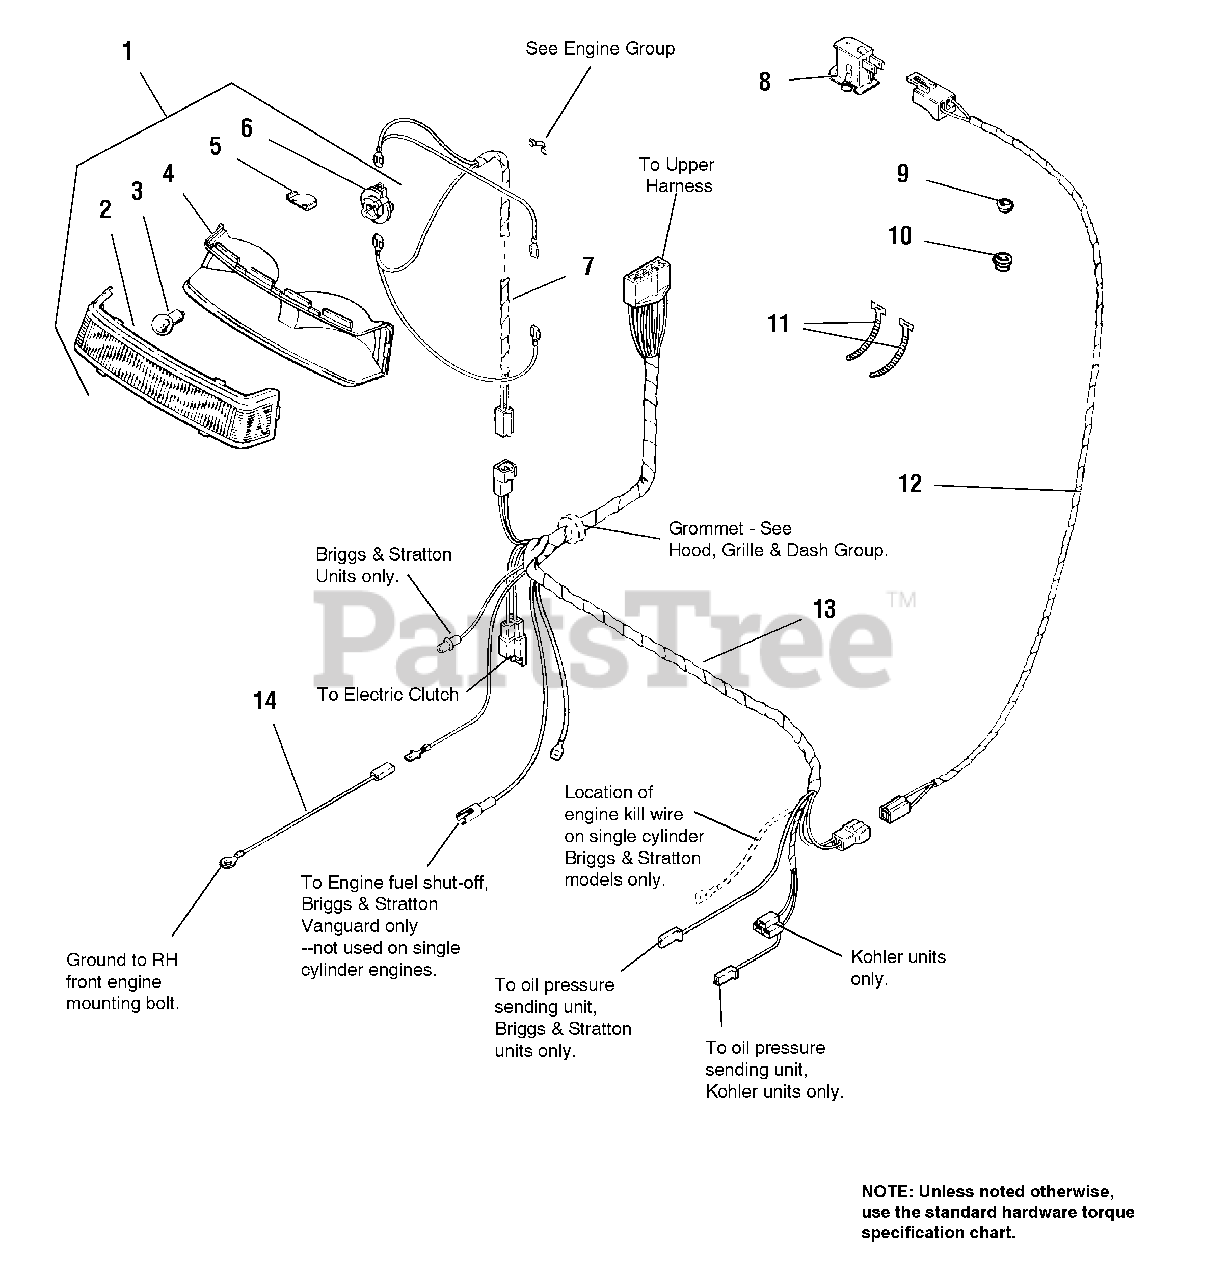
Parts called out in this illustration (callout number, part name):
1	HEADLIGHT ASSY.
2	LENS, Headlight
3	BULB, Headlight, 12.8V
4	BEZEL, Headlight
5	HEAT SHIELD
6	SOCKET, Bulb
7	WIRE ASSY., Headlight
8	SWITCH, Seat, Operator Present
9	BUSHING, Snap, Small
10	BUSHING, Snap, Large
12	WIRE ASSY., Seat Switch
13	HARNESS ASSY., Lower
14	WIRE ASSY., Engine Ground
